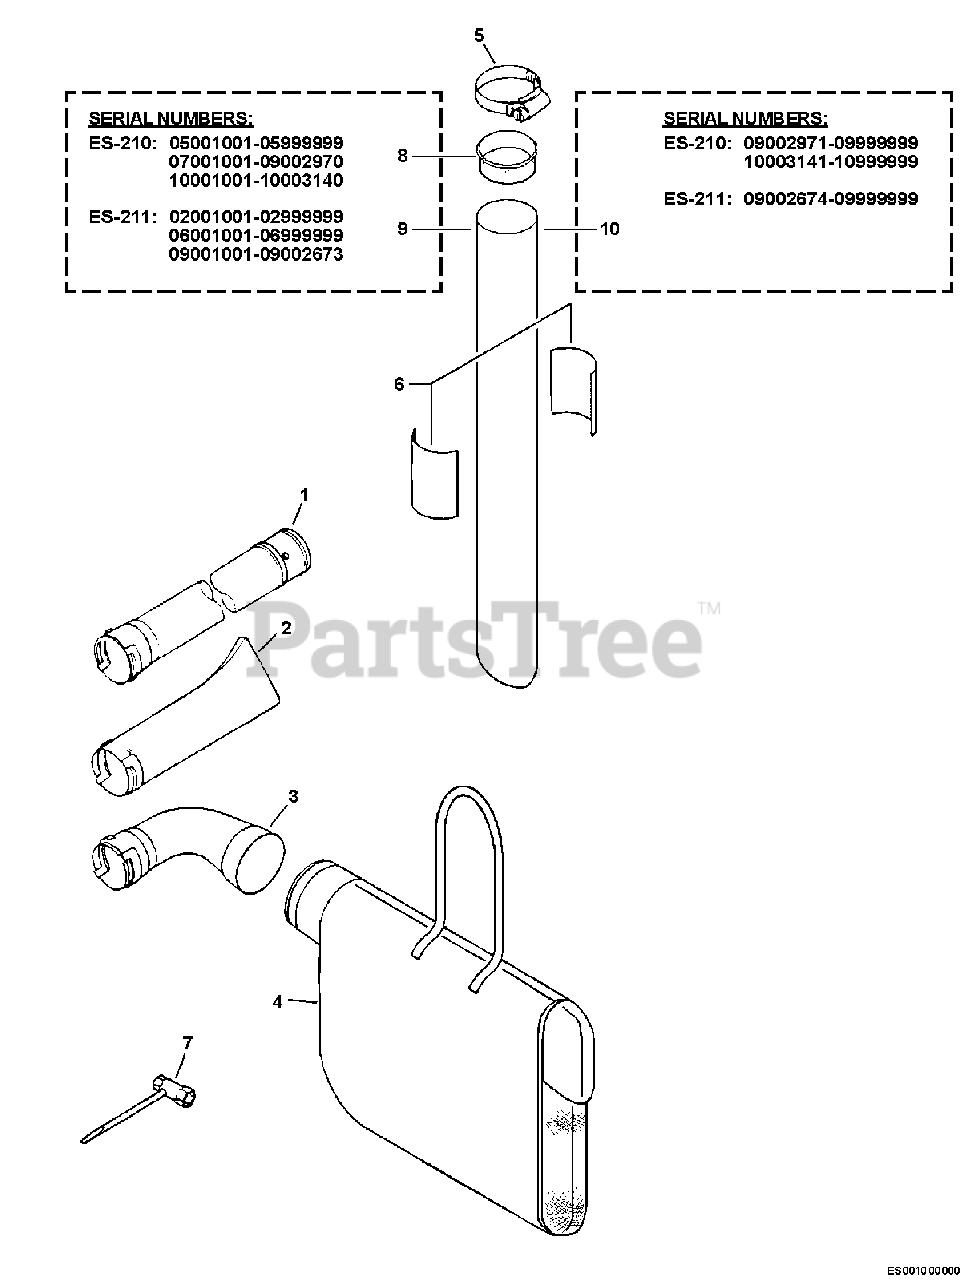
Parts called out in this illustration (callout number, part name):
1	TUBE, BLOWER - STRAIGHT
2	TUBE, BLOWER - NOZZLE
4	BAG, DUST
6	LABEL - SHRED 'N' VAC
7	T-WRENCH 13×19×180
9	TUBE, VACUUM
10	TUBE, VACUUM
